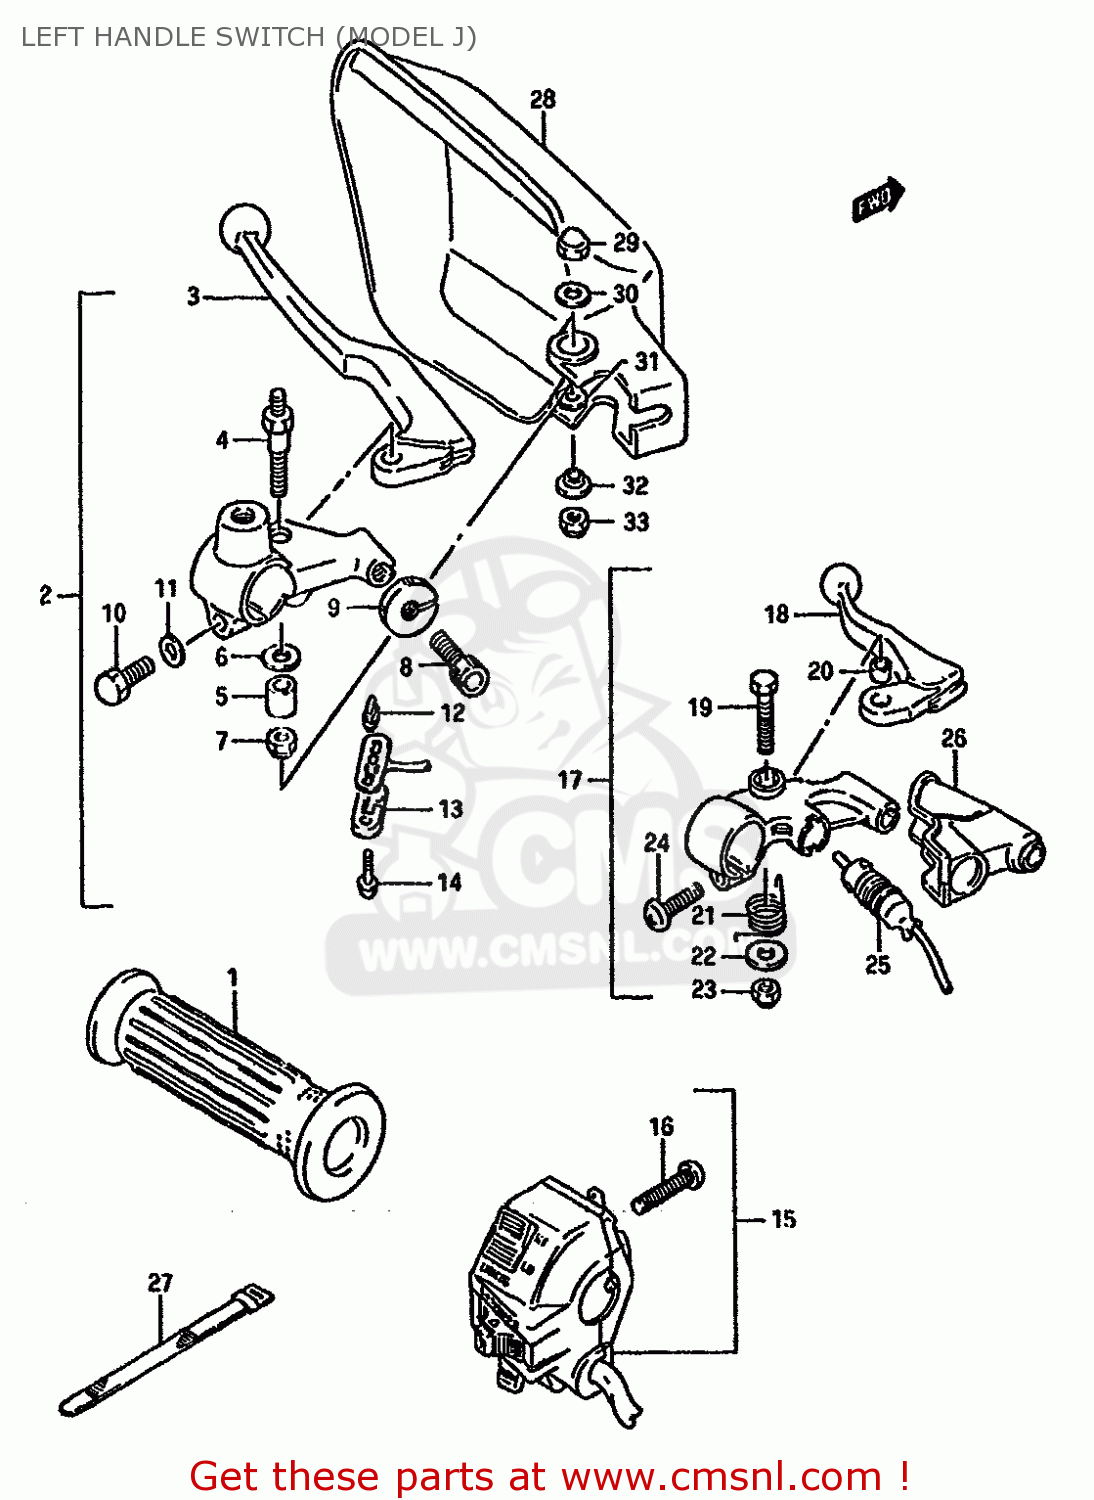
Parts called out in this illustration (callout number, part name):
1	GRIP,LEFT
2	LEVER ASSY,CLUTCH
3	LEVER,CLUTCH
4	BOLT,LEVER SET
5	SPACER,LEVER SET
6	WASHER,LEVER SET
7	NUT
8	ADJUSTER,CABLE
9	NUT,LOCK
10	BOLT
11	WASHER
12	CONTACT,SWITCH
13	COVER,FR BK TERMINAL BASE
14	SCREW
15	SWITCH ASSY,HANDLE LH
16	SCREW
17	LEVER ASSY,DECOMP
18	LEVER
19	BOLT
20	SPACER
21	SPRING
22	WASHER
23	NUT
24	SCREW
25	SWITCH
26	COVER,DECOMP,DUST
27	CLAMP(L:120)
28	GUARD,KNUCKLE LH (RED)
29	NUT 6MM
30	WASHER (6.5X20X1.6)
31	WASHER(6.5X16X1.2)
32	WASHER
33	NUT
34	WASHER(6.5X16X1.2)
35	WASHER
36	NUT
